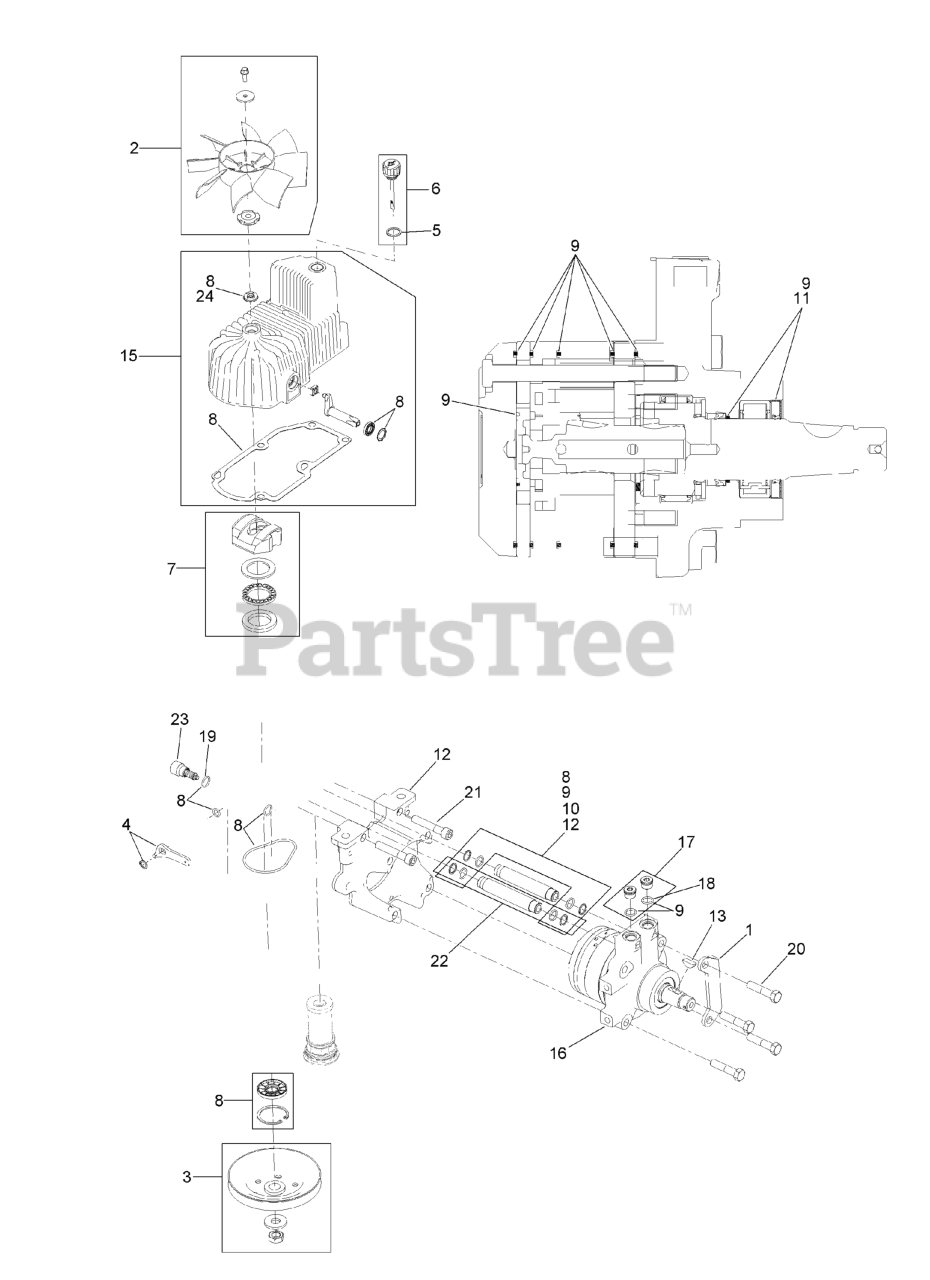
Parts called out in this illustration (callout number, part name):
1	MOUNT-SHOE, HORSE
2	FAN KIT
3	PULLEY KIT
4	HANDLE-BYPASS VALVE, HYDRO
5	GASKET-DIPSTICK, HYDRO
6	DIPSTICK-HYDRO W/GASKET
7	SWASH BLOCK KIT
8	PUMP SEAL KIT
9	MOTOR SEAL KIT
10	TUBE SEAL KIT
11	OUTPUT SHAFT SEAL KIT
12	NOSE CUP-UHT
13	KEY-WOODRUFF
15	HOUSING-HYDRO, RH
16	MOTOR-HYDRAULIC, RH 280CC
17	MAGNETIC PLUGS SERVICE KIT
19	O-RING-CHECK VALVE
20	SCREW HH
21	SCREW-HSH
22	HYDRAULIC TUBE KIT
23	SHOCK VALVE, 16CC HYDRO
24	SEAL-FAN DRIVE
25	Kit, Pump Section 16Cc RH
26	Kit, Rotating Grp 16Cc RH
99	PULLER-PULLEY
